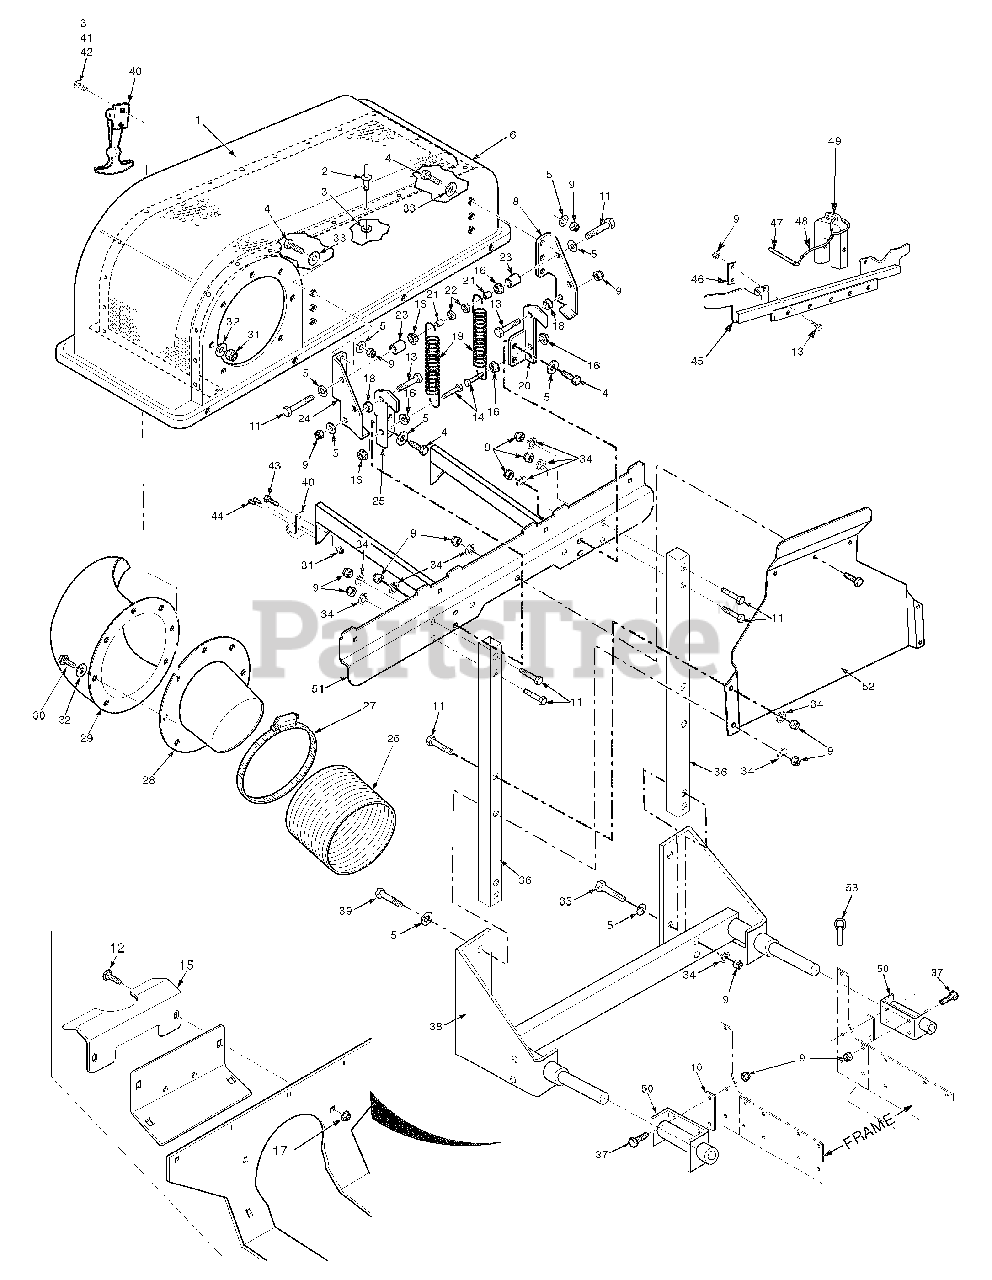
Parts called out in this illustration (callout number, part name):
1	Screen, Catcher Hood
2	Pop Rivet, 3/16 x .652
3	Flatwasher, 3/16-.196 x .469 x .048
4	Bolt, Hex Head 3/8-16 x 1-1/4"
5	Flatwasher, 3/8-.391 x .938 x .105
6	Hood Assembly, GC-STT
7	Bolt, Hex Head 3/8-16 x 2-3/4"
8	Hinge, Upper LH
9	Nut, Elastic Stop 3/8-16
10	Spacer, Hitch
11	Bolt, Hex Head 3/8-16 x 2-1/4"
12	Bolt, Carriage 5/16-18 x 1.00"
13	Bolt, Hex Head 3/8-16 x 1-1/2"
14	Bolt, Hex Head 3/8-16 x 1-3/4" Grade 8
15	Support Bracket, Catcher
16	Nut, Serrated Flange 3/8-16
17	Nut, Hex Serrated Flange 5/16-18
18	Bushing, Hopper Pivot
19	Spring, Hood Hinge
20	Hinge, Lower LH
21	Spacer
22	Locknut, 3/8-16
23	Spacer
24	Hinge, Upper RH
25	Hinge, Lower RH
26	Hose, 8" Dia. x 60.5"
27	Clamp, 8-5/8" Max Dia.
28	Tube, Filler GC-STT
29	Elbow, GC-STT
30	Bolt, Hex Head 5/16-18 x 1-1/4"
31	Nut, Elastic Stop 5/16-18
32	Flatwasher, 5/16-.375 x .875 x .083
33	Flatwasher, 3/8- .406 x 1-1/2" x .179
34	Lockwasher, 3/8 Spring
35	Bolt, Hex Head 3/8-16 x 3-3/4"
36	Tube, Upright
37	Bolt, Hex Head 3/8-16 x 1"
38	Frame Weldment
39	Bolt, Hex Head 3/8-16 x 2-1/2"
40	Latch
41	Screw, #10-32 x 3/4"
42	Nut, Elastic Stop #10-32
43	Bolt, Hex Head 5/16-18 x 3/4"
44	Rivet, 3/16 x .402 POP
45	Support Weldment, Front Weights
46	Clamp, Bar
47	Pin, 1/2 x 6-1/4"
48	Lanyard, Weight Pin
49	Weight Assembly
50	Hitch Bracket Weldment
51	Support Weldment, Bag Frame
52	Heat Shield
53	Quick Pin
